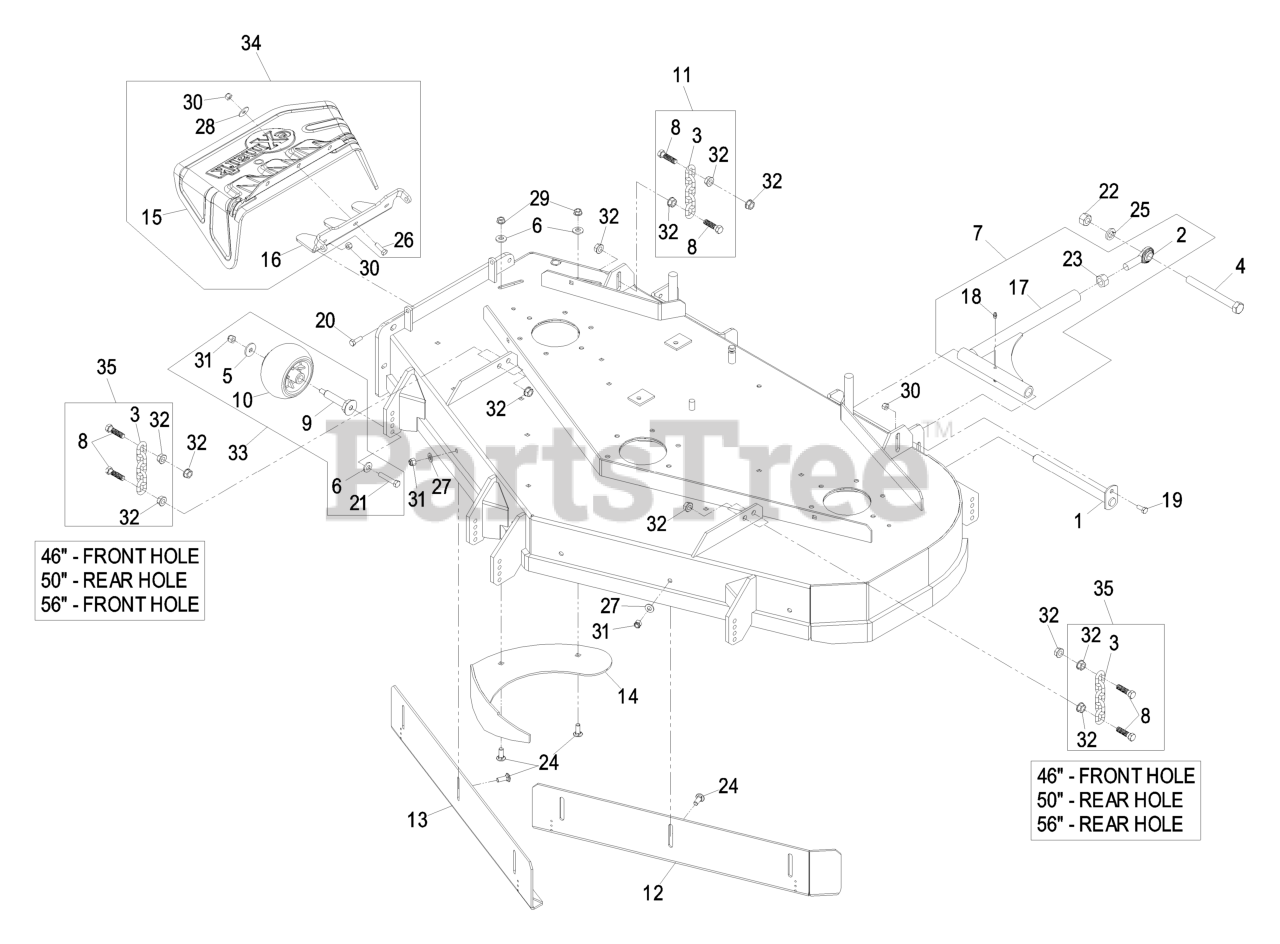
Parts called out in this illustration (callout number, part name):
1	PIN-STRUT
2	BALLJOINT-SPHERICAL
3	CHAIN-LIFT, DECK
6	WASHER-BELLEVILLE
7	STRUT ASM
8	SCREW-HH
10	ROLLER-SCALP, ANTI
11	DECK CHAIN ASM
14	WLD,DOGLEG 465
15	CHUTE,DISCHARGE
16	BRACKET,DISCHARGE CHUTE
18	FITTING-GREASE
19	SCREW-HH
20	SCREW-HH
21	SCREW-HH
22	NUT-HEX
23	NUT-HEX
24	SCREW-CARR
25	WASHER-LOCK
26	SCREW-CARR
27	WASHER-FLAT
28	WASHER-FLAT
29	NUT-HHF, WHIZ
30	NUT-LOCK, NI
31	NUT-LOCK, NI
35	DECK CHAIN ASM
